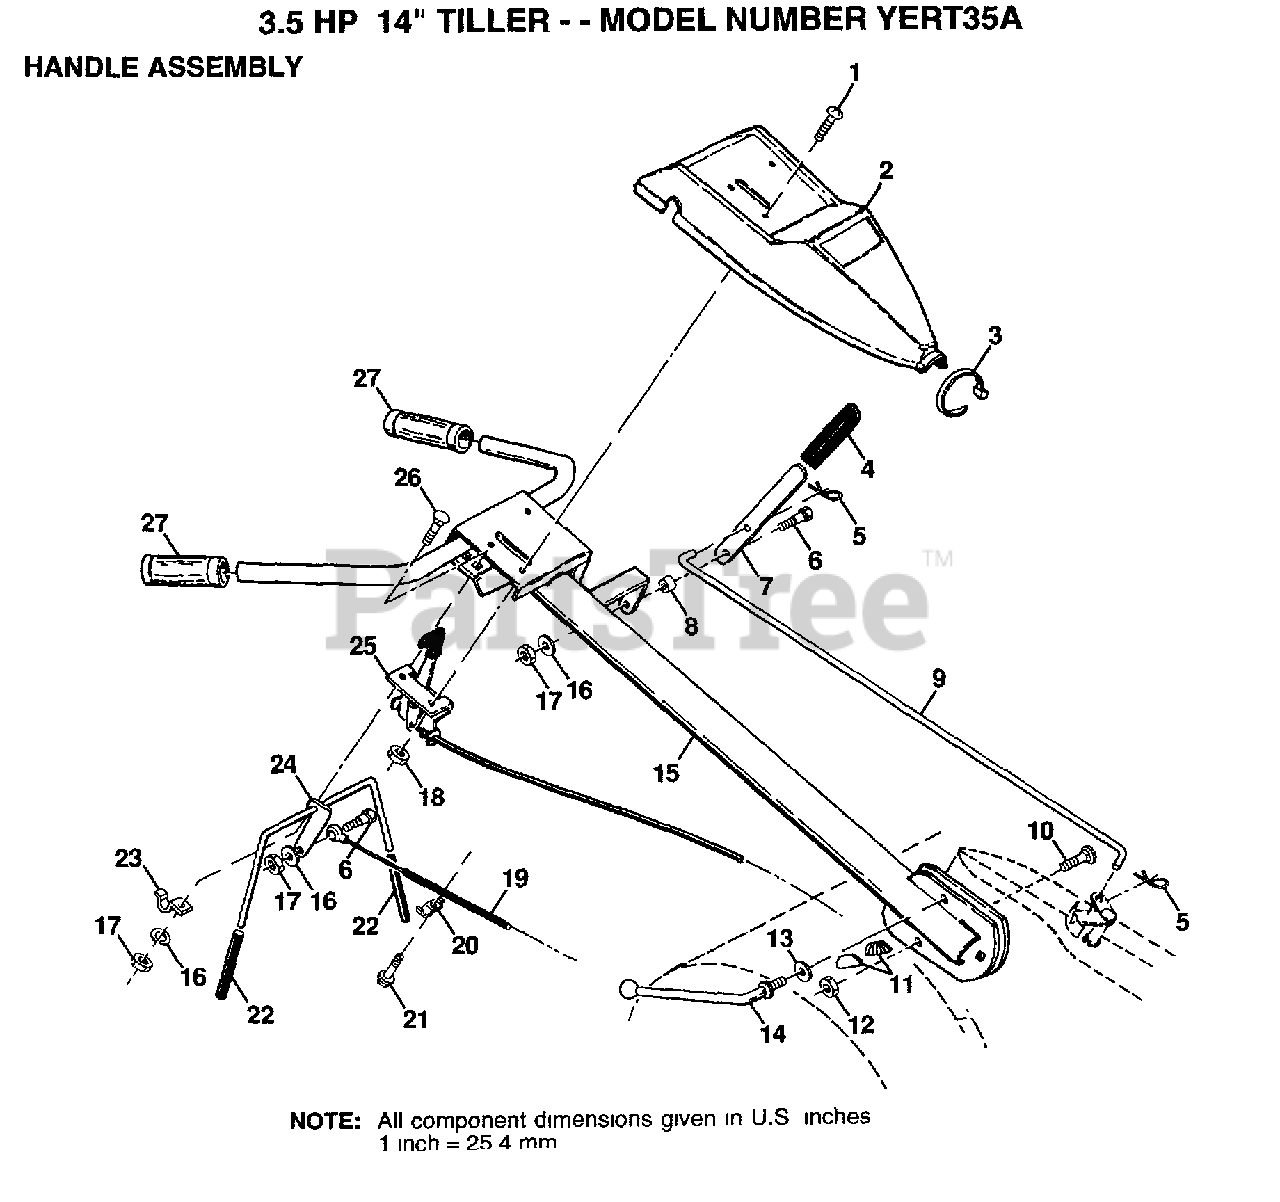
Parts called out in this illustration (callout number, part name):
1	SCREW
2	PANEL,CONT TI
3	TIE CABLE CRT
4	GRIP T
5	RETAINER M
6	SHOULDER BOLT ST
7	SHIFT HANDLE CRT
8	GROMMET CRT
9	SHIFT ROD CRT
10	BOLT D
11	LOCK CRT
12	LOCKNUT
13	WASHER CRT
14	LEVER LOCK CRT
16	LOCKWASHER
19	CABLE.CLUTCH.CRT
20	CONDIUT CLIP T
22	GRIP BAR CRT
24	"ASSY CONTROL, BAR"
25	"CONT,THROTTLE"
26	BOLT
